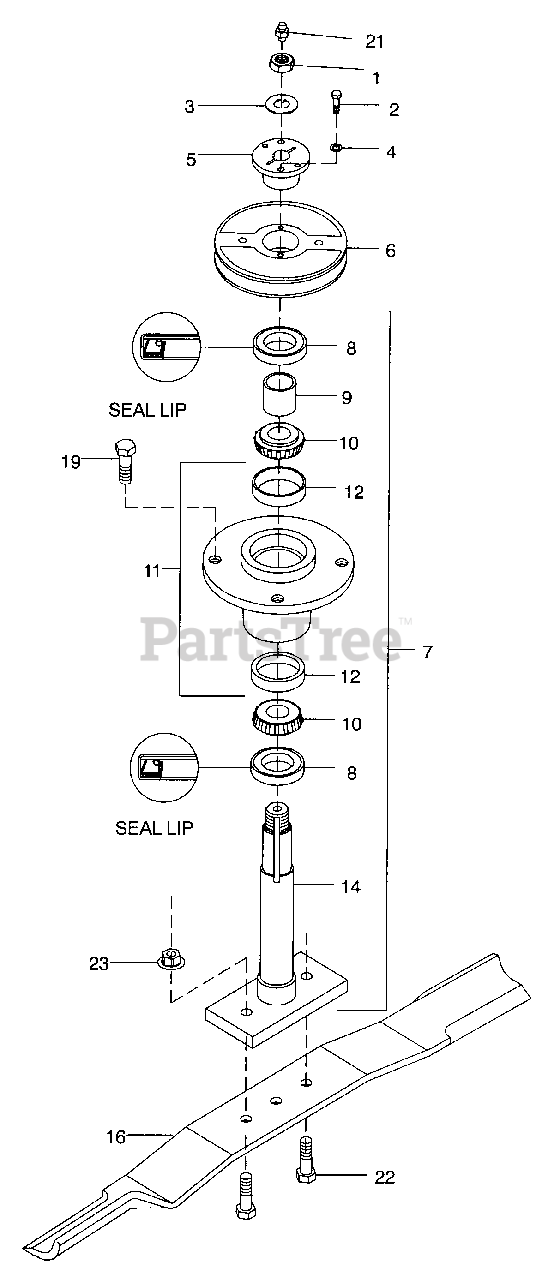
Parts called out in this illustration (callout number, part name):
1	7/8-18 UNF Hex jam nut
2	1/4 NC x 1 Hex head cap screw GR5
3	.929 x 1.41 Lockwasher
4	1/4 Standard lockwasher
5	H 1" Straight bore bushing with key P.I.
6	Sheave, Model 483
6	Sheave, Model 484
7	Spindle assembly
10	Bearing cone
11	Spindle housing with cups
12	Bearing cup
14	Spindle shaft with keyway
16	CW High-suction blade Model 484
16	CW High-suction blade Model 483
19	1/2 NF x 1-1/4 Hex head cap screw GR5
21	1/4-28 Tapered
22	1/2 NC x 1-1/2 Hex head cap screw GR5
23	1/2 NC Hex flange locknut
